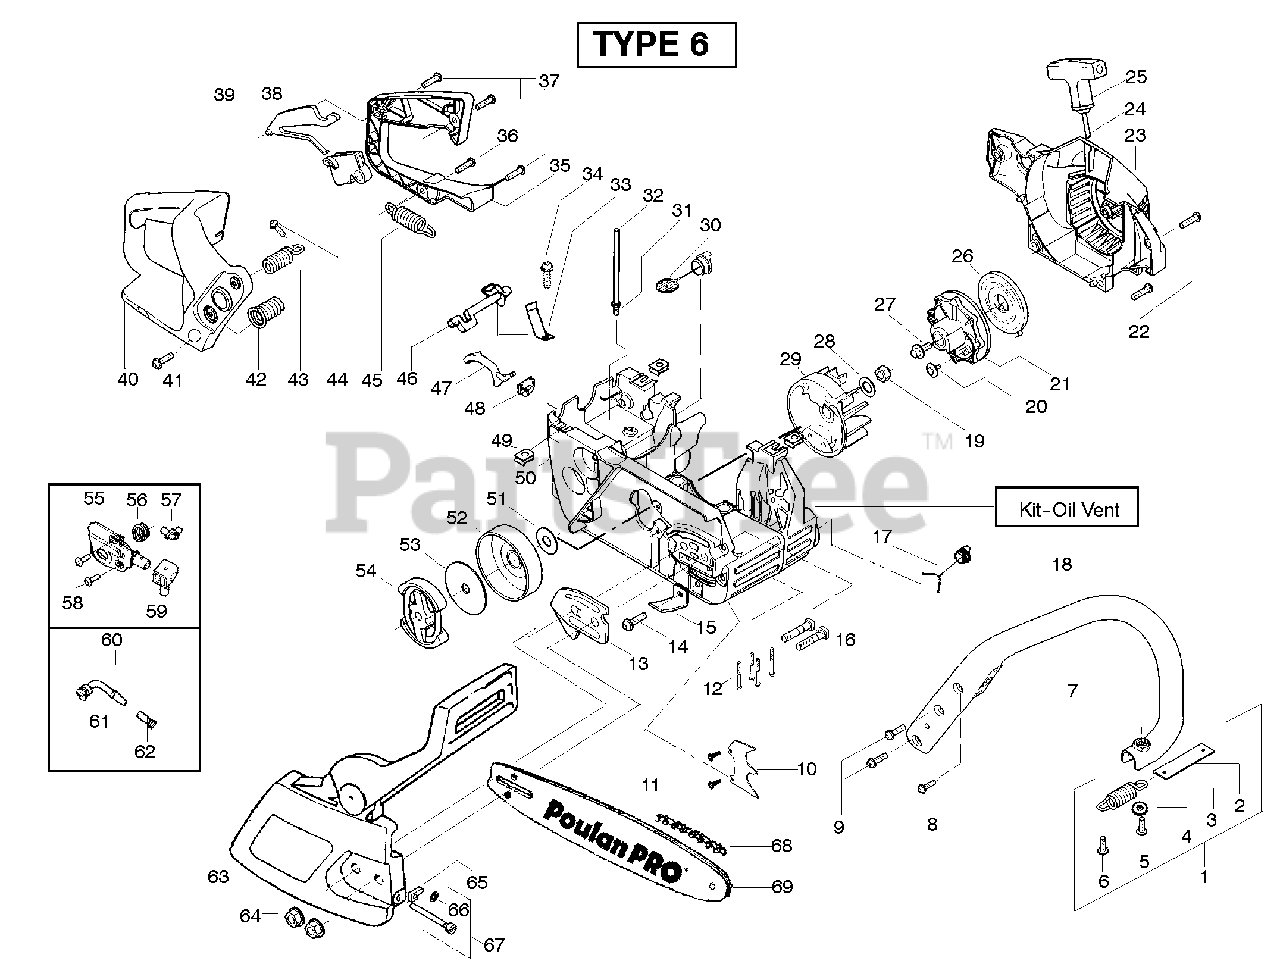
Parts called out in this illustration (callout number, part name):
1	Assy.-Isolator
2	Limiter Strap
3	Spring-Isolator
4	Washer
7	Front Handle
10	Kit-Spike Assy
13	Plate-Bar Mount.
15	Chain Catcher
16	Bolt-Bar
17	Assy-Oil Cap
18	Kit-Oil Vent
19	Nut-Flywheel
21	Starter Pulley
23	Housing-Fan
24	Kit - Rope
25	Handle-Starter
26	Spring-Recoil
28	Washer-Flywheel
29	Assy-Flywheel
30	Assy-Fuel Cap
31	Fitting-fuel line
32	Kit-Fuel line (large)
33	Spring-Switch
35	Cover-Rear Handle
38	Throttle Lockout
39	Trigger-Throttle
40	Handle - Rear
41	Screw
42	Assy Isolator-lower
43	Kit-Isolator (Upper)
45	Spring-Isolator
46	Lever-Switch
47	Lever-Choke
48	Grommet-Knob
49	Nut-"U"-Type
50	Assy-Chassis, Gold
50	Assy-Chassis, Black
51	Washer-Thrust
52	Assy.-Clutch Drum w/bearing
53	Washer-Clutch
54	Assy. Clutch
55	Kit - Oil Pump
56	Gear-Worm Spring
57	Elbow-Oil Pickup
59	Seal Block
60	Assy-Oil Pick-up
61	Pick-up Oiler
62	Filter-Oil
63	Assy.-Chain Brake
64	Nut-Bar Mounting
65	Pin-Bar Adjust
66	Retainer
67	Kit-Bar Adjusting
68	Chain, 16"
68	Chain, 18"
69	BAR, 16" Standard
69	BAR, 18" Standard
69	BAR, 18" Quick Adjust
69	BAR, Quick Adj. pro lam
